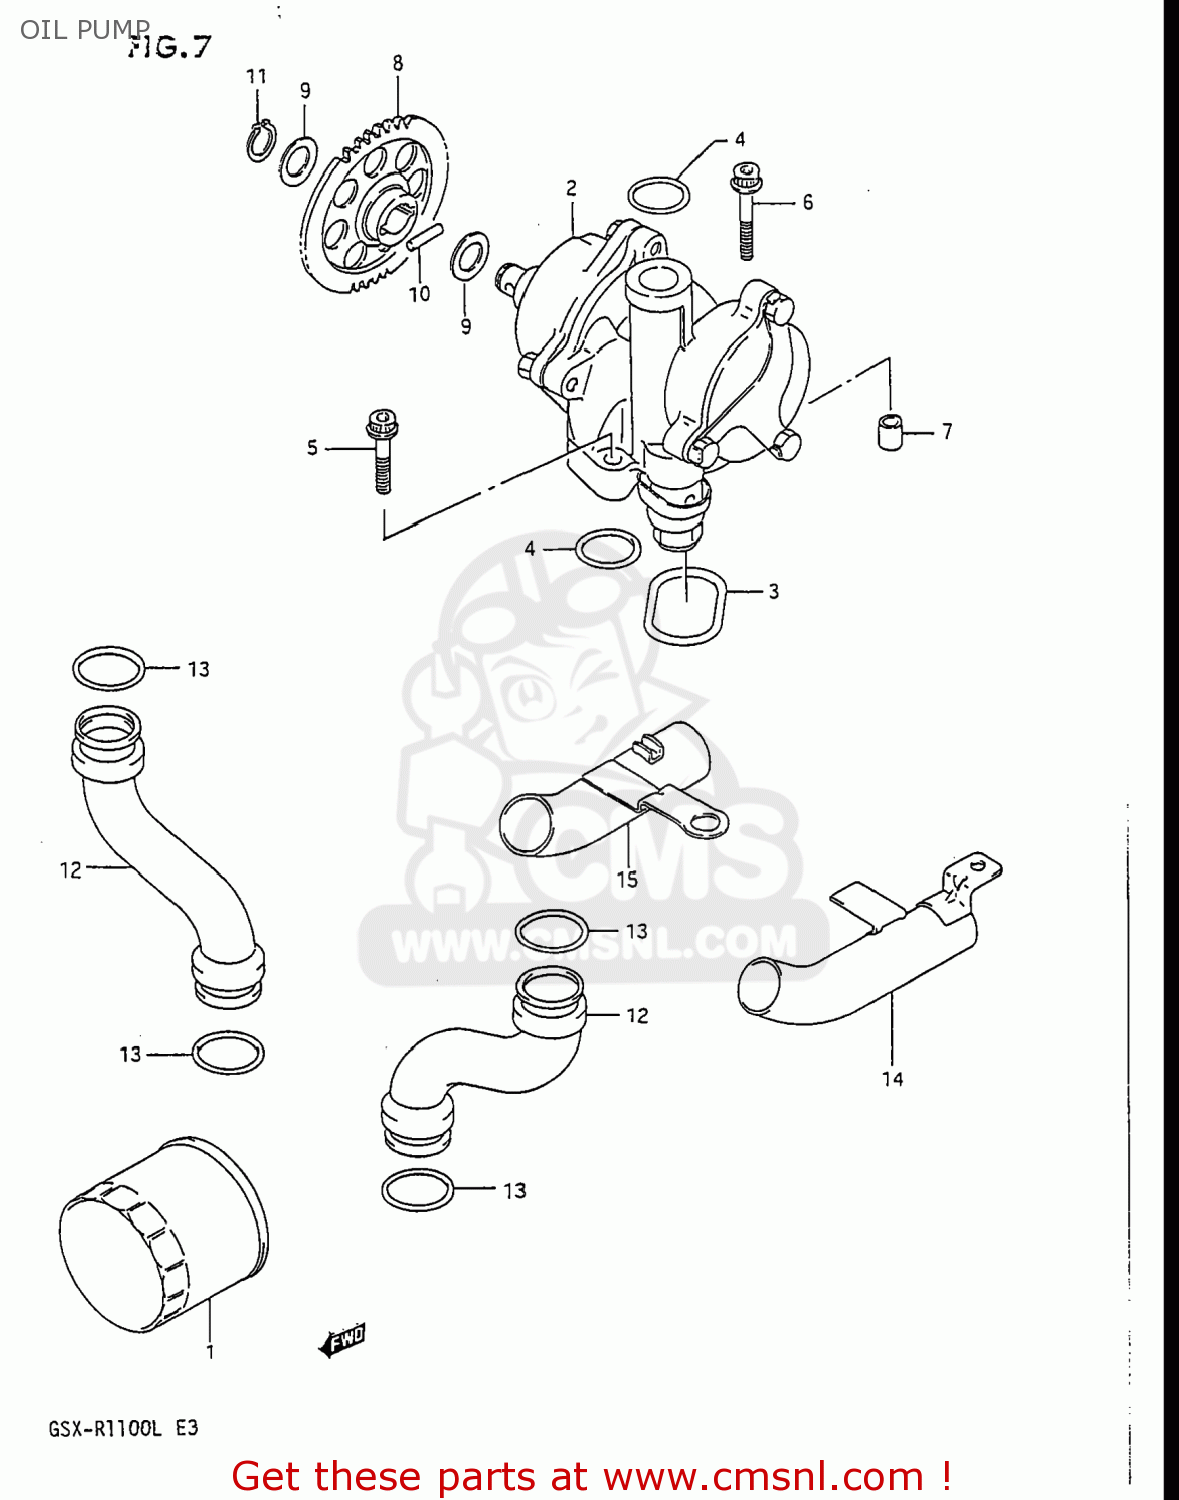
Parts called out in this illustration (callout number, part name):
1	FILTER,OIL
2	PUMP ASSEMBLY,OIL
3	O RING,OIL PUMP
4	O RING(D:3.2,ID:17.8)
5	BOLT
6	BOLT
7	PIN
8	GEAR,OIL PUMP DRIVEN
9	SHIM
10	PIN(5X18)
11	CIRCLIP
12	PIPE,OIL OUTLET
13	O RING(D:3.7,ID:21.7)
14	PIPE COMP,OIL OUTLET,UPPER
15	PIPE,OIL,OUTLET,UNDER
